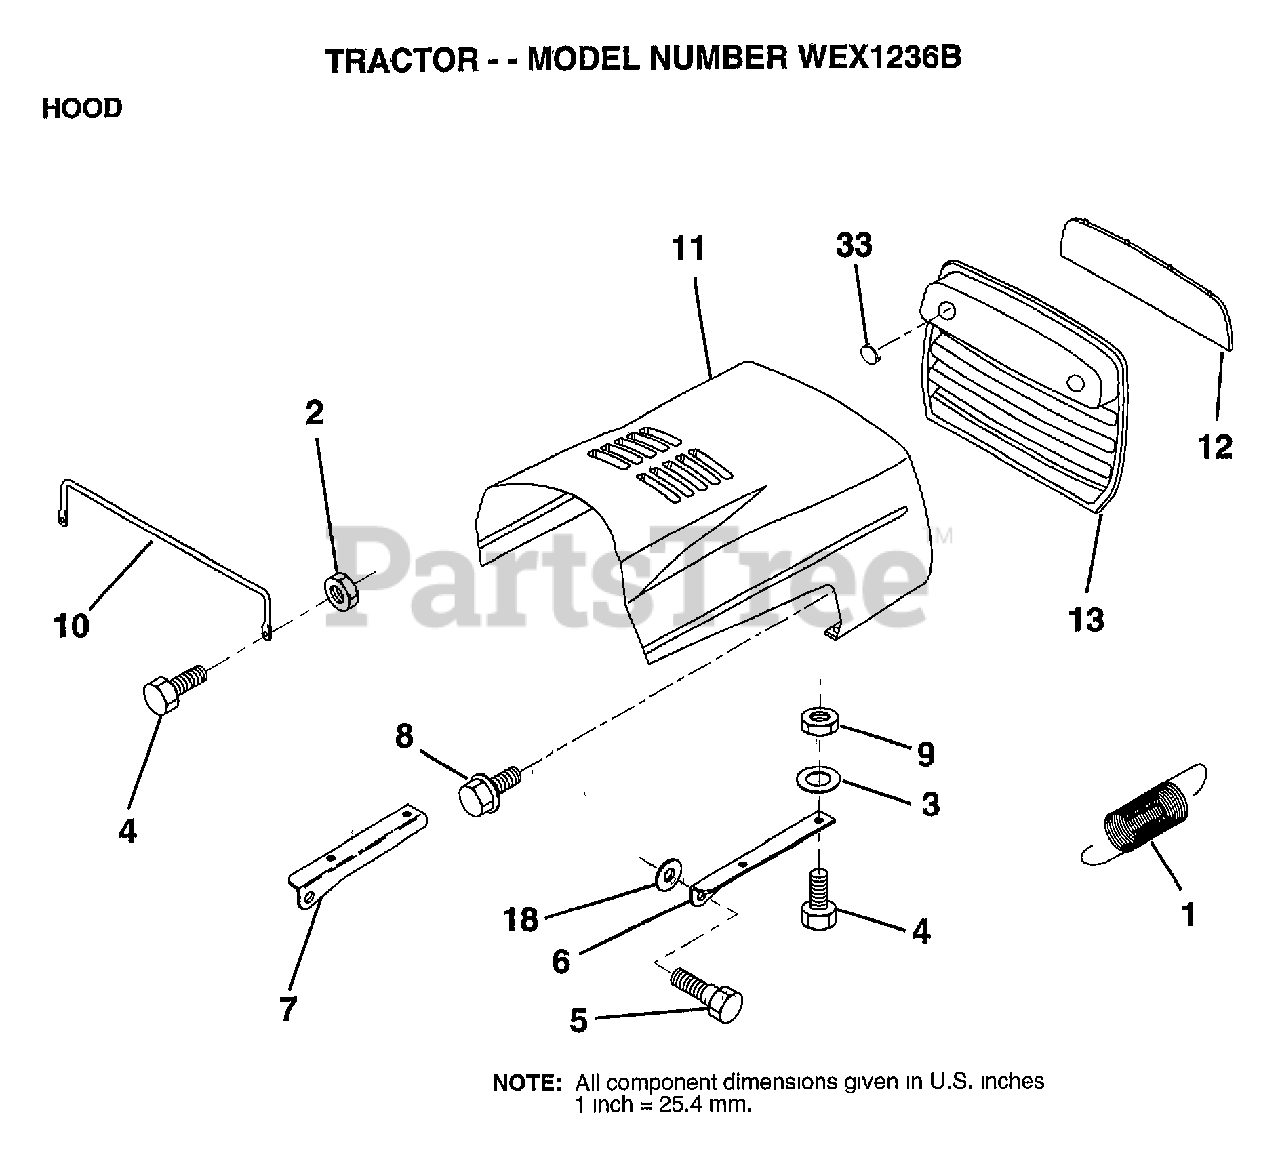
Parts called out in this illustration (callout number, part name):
1	EXT SPRING
2	NUT
3	WASHER
5	BOLT.SHLD.5/16-18
6	BRKT HOOD RH
7	BRKT HOOD LH
8	SCREW SLTD HXHD
9	NUT
10	"BRACE,HOOD"
11	HOOD.IMPREG.MS550
12	LENS
13	GRILL
18	WASHER
